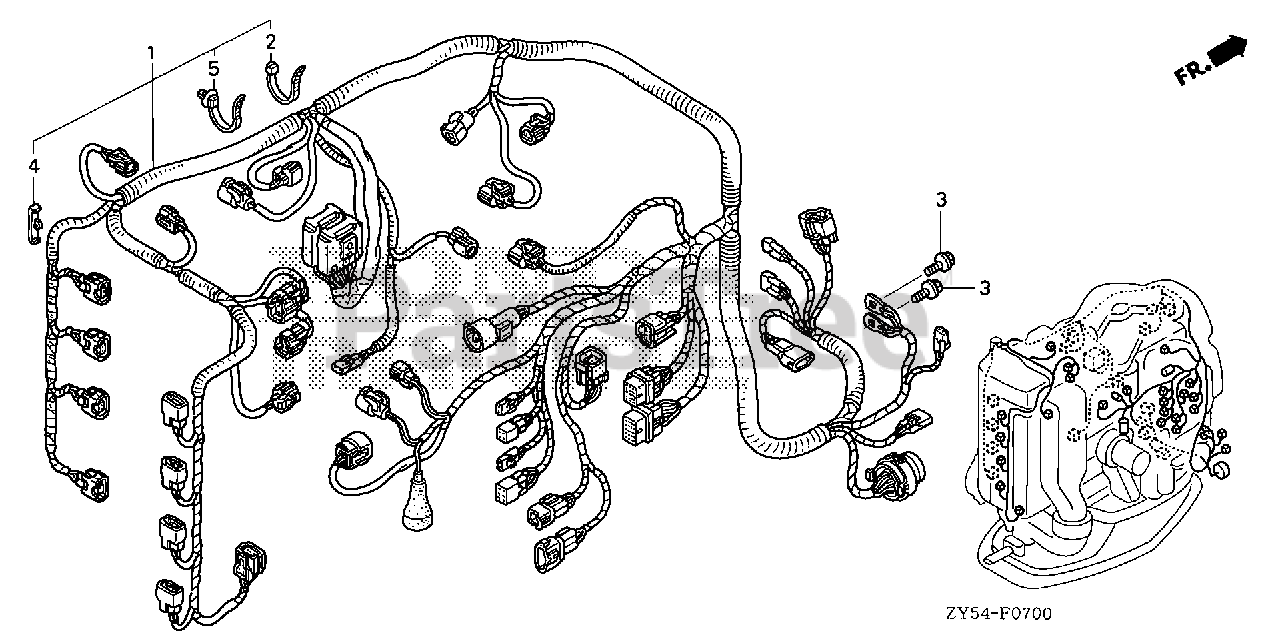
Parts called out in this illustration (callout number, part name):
1	WIRE HARNESS ASSY., MAIN
2	BAND, WIRE
3	BOLT, FLANGE (6X12)
4	CLIP, WIRE HARNESS
5	CLIP, HARNESS BAND (145MM) (BLACK)
